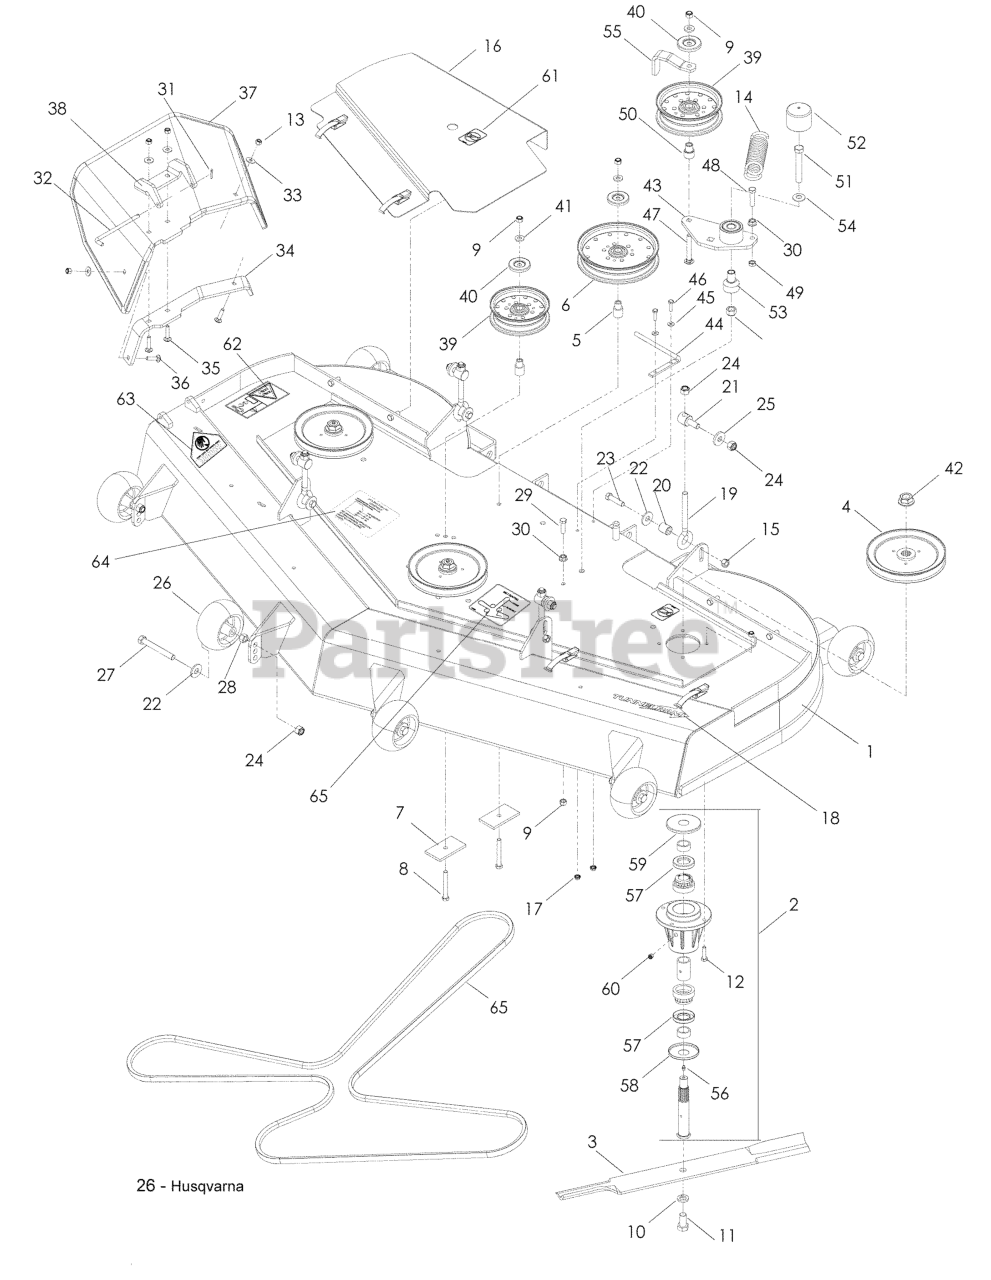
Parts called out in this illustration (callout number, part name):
1	DECK W/DECALS 72" HUS
2	HOUSING ASM, 52/61
3	BLADE OEM - 25"
4	PULLEY, 72
5	IDLER BUSHING
6	PULLEY - IDLER 7"
7	SUPPORT PLATE
8	HCS 3/8C X 3
9	NUT 3/8-16 NYLOC
10	LOCKWASHER 5/8
11	HCS 5/8F X 1 1/4
12	HCS 5/16C X 1 1/4
13	NUT 5/16 NYLOC
14	DECK SPRING
15	NUT 7/16C CENTERLOCK
16	BELT SHIELD 72 RH
17	NUT 1/4-20 HEX FLG LK ZD
18	DECAL, TUNNEL RAM 8"
21	SWIVEL, DECK HEIGHT ADJ
22	WASH USS FLAT 1/2
23	HCS 7/16 - 14 X 1 3/4
24	NUT 1/2-13 HEX NYLOC ZD
25	WASHER-.533IDX1.37OD
26	GAUGE WHEEL
27	HCS 1/2-13 X 4 GR 5 ZD
28	NUT HEX 1/2
29	HCS 3/8C X 1 1/4 GR5
30	NUT 3/8C WHIZ
31	RP_COTTER PIN 1/8 X 3/4
32	PIN, CHUTE PIVOT
33	WASHER 5/16 FLAT
34	BRACKET REINF, CHUTE
35	RHSNB 5/16-18 X 1-1/2 GR 5 ZD
36	BOLT, CARRIAGE 5/16X1-1/4
37	CHUTE, RUBBER DISCHARGE 72"
38	PIVOT BRACKET - RUBBER CHUTE
39	IDLER PULLEY
40	DUST SHIELD
41	WASHER, 3/8 THICK
42	NUT FLANGE 3/4-16
43	ARM-IDLER W/BRG
44	BELT GUIDE
45	WASHER 1/4 SAE
46	HCS 1/4 X 1
47	RHSNB 3/8-16 X 2.75
48	HCS 3/8-16 X 1-1/2
49	NUT 3/8-16 HEX JAM
50	BUSHING, IDLER
51	HCS 1/2C X 3 1/4
52	CAP, VINYL
53	PIVOT, BEARING
54	CONTACT BELLSPR 1/2
55	GUIDE, BELT
56	ZERK
57	SHAFT SEAL
58	BOTTOM DUST CAP
59	TOP DUST CAP
60	PLUG-VENTED
61	DECAL, NO STEP
62	DECAL, EURO SEVERING
63	DECAL, CPSC
64	DECAL, ANTI SCALP
65	DECAL, BELT ROUTING
66	BELT, DECK 72 TRD
